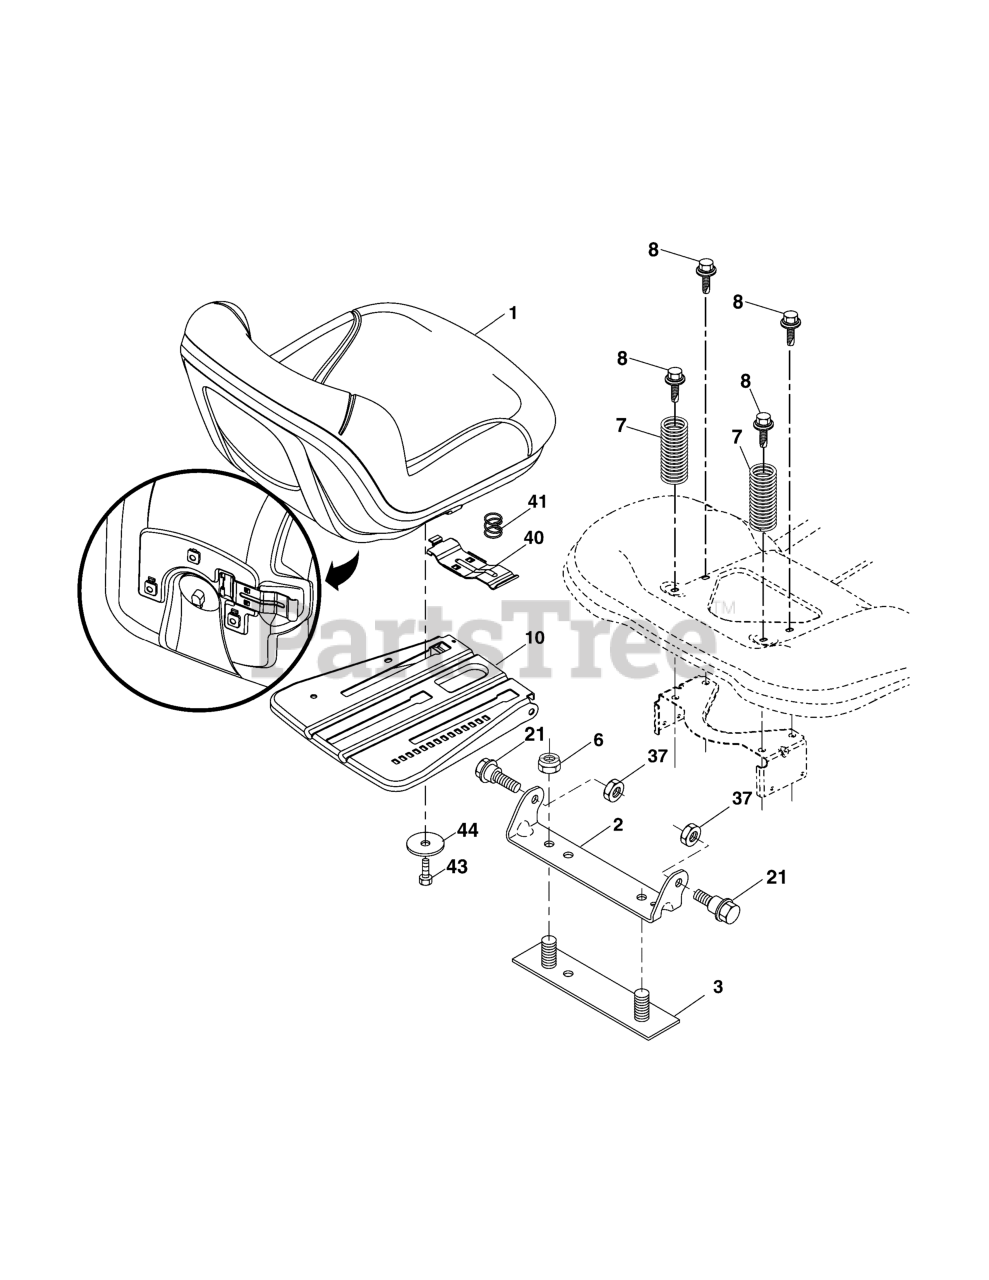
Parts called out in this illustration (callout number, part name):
1	Seat
2	Bracket Pivot Fender
3	Strap, Asm Fender
6	Nut, Lock w/Ins. 3/8-16 unc
7	Spring, Seat Cprsn
8	Bolt 5/16-18 unc x 3/4 w/Sems
10	Pan, Seat
21	Bolt, Shoulder 5/16-18
37	Nut, Lock 5/16-18 unc
40	Handle Slide
41	Spring Latch
43	Bolt 3/8-16 unc x 3/4
44	Washer 13/32 x 2 3/8 x 12 Ga.
